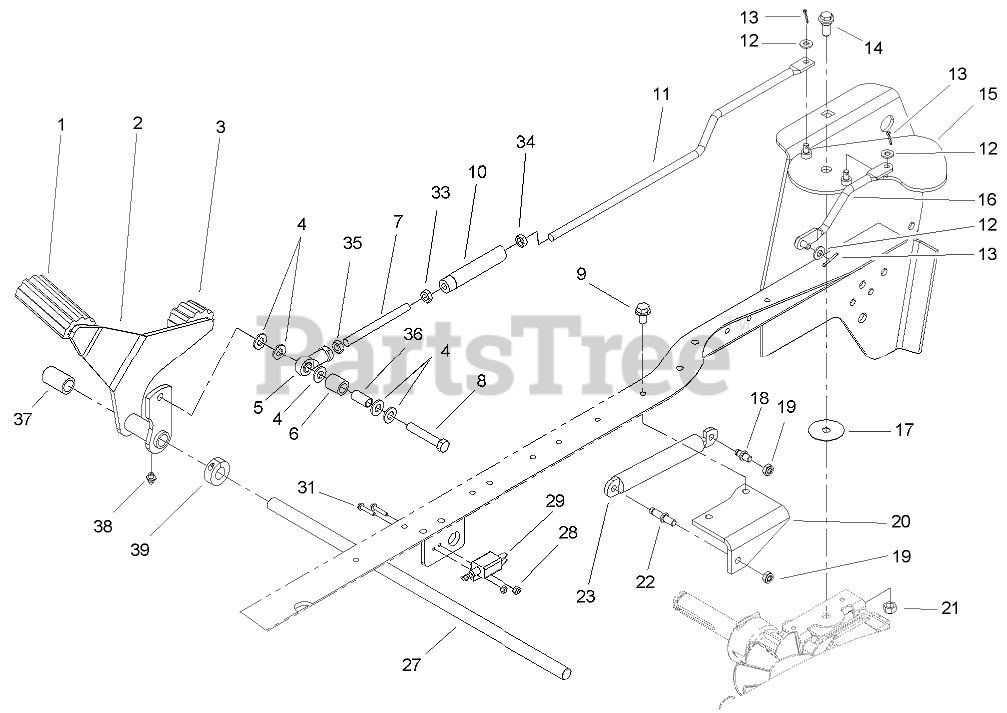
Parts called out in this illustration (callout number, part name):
1	PAD-PEDAL
2	HYDRO PEDAL ASM
3	PAD-PEDAL
4	WASHER-FLAT
5	END-ROD, FEMALE
6	SPACER-INTERLOCK
7	ROD-HYDRO, FRONT
8	SCREW-HH
9	SCREW-HWHTF
10	TURNBUCKLE
11	ROD-HYDRO, REAR
12	WASHER-PLAIN
13	PIN-COTTER
14	BOLT-SHOULDER
15	CRUISE PLATE ASM
16	BELL CRANK ROD ASM
17	SPACER-CRUISE
18	ARM-CONTROL, PIN DAMPER
19	NUT-LOCK, NI
20	BRACKET-DAMPER
22	PIN-BRACKET, DAMPER
23	DAMPER-GAS
27	SHAFT-PIVOT, PEDAL
28	NUT-LOCK
29	SWITCH-ADJUSTABLE
31	SCREW-SHWH
33	NUT-HJ
34	NUT-JAM
35	NUT-JAM
36	SLEEVE-BEARING
37	SPACER
38	FITTING-GREASE
39	COLLAR-LOCKING
